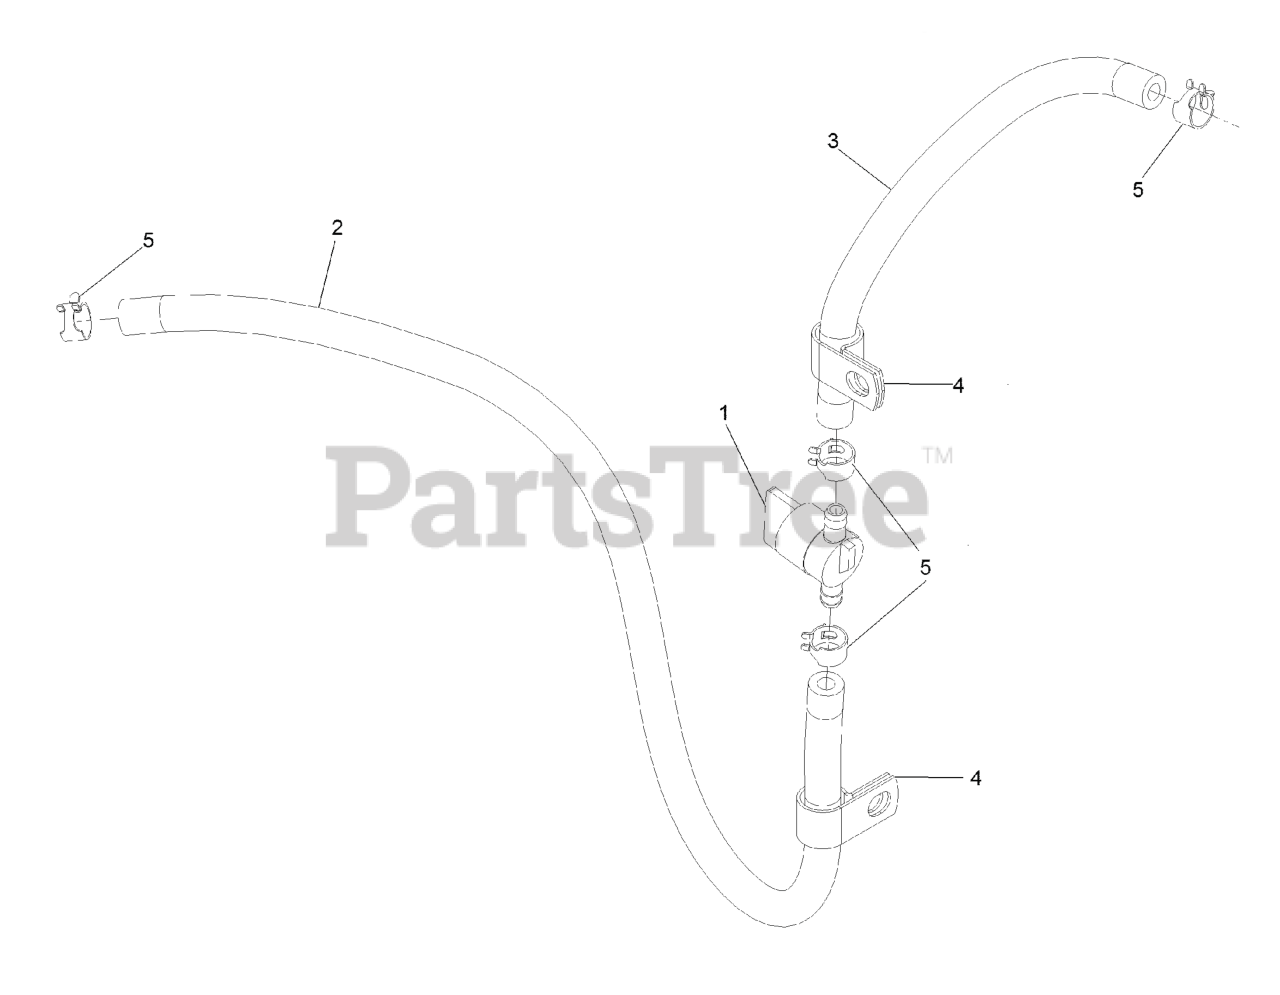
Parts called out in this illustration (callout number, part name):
1	VALVE-FUEL
2	HOSE-FUEL
3	HOSE-FUEL
4	CLAMP-R
5	CLAMP-HOSE
